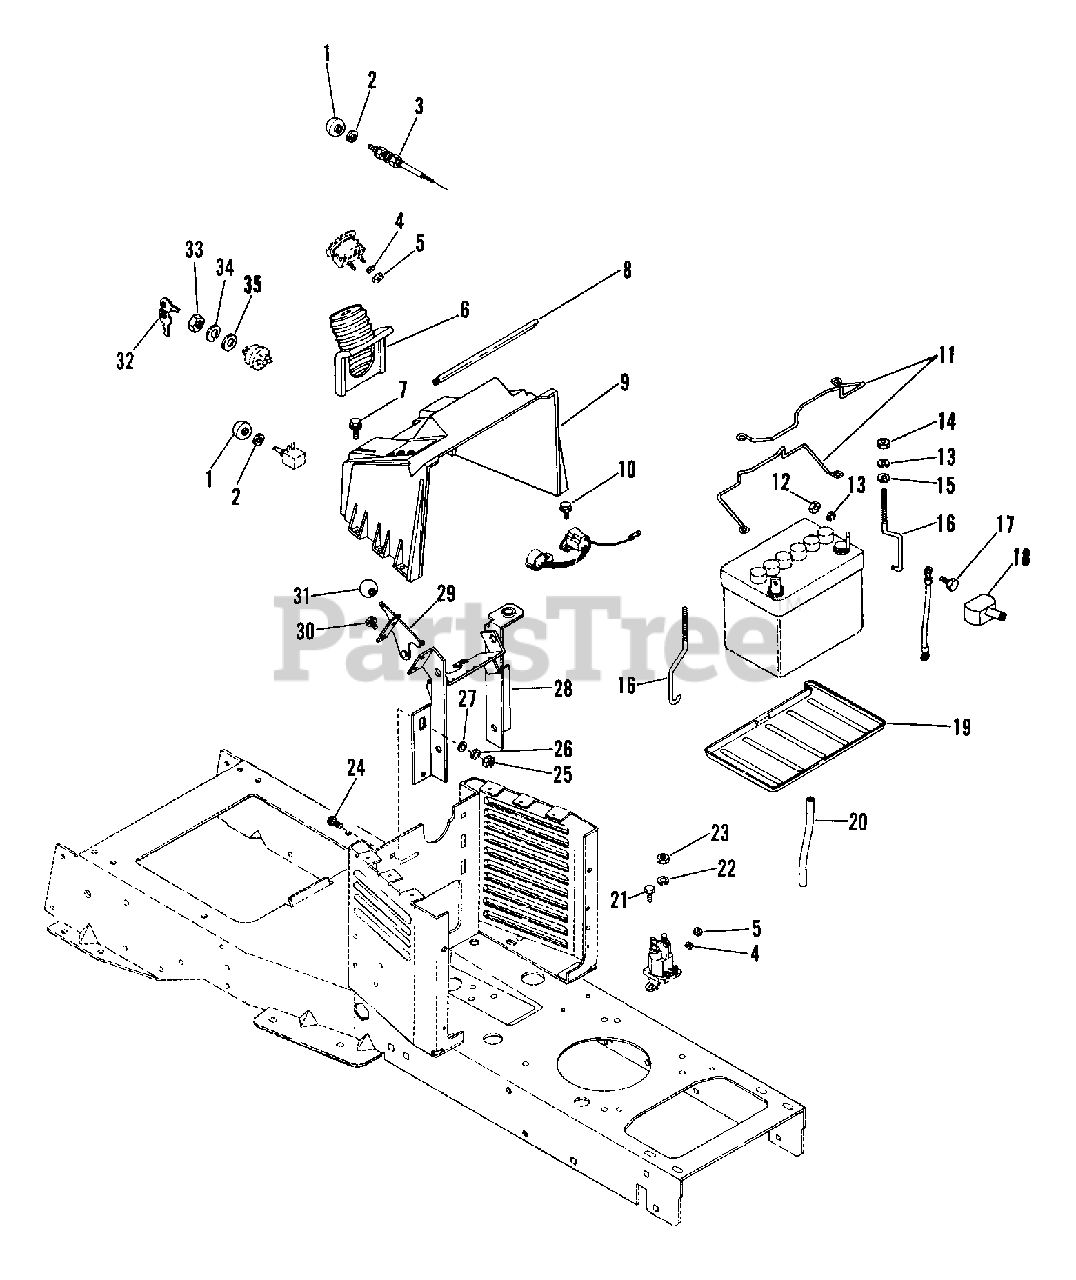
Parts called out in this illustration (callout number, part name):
1	PUSH/PULL CONTROL KNOB
2	WSHR-FL-STL .382X.812X.023 PL
3	CHOKE CONTROL
4	WSHR-LK-EXT #10 ID X .022
5	NUT 10-32 PL
6	STEERING COLUMN BOOT
7	SCR-TAP 10-16X.50 HWH PL AB
9	DASH ASSEMBLY
10	SCR-TAP 10-24X.375 CRPH 1A
11	HOLD DOWN
12	NUT-HEX .250-20 PL
13	WSHR-LK .250X.077 HVY PL
14	NUT-LK-NYL .250-20 PL
15	WSHR-FL-STL.281X.62X.065 PL
16	TIE DOWN
17	BLT-HEX .25-20X.63 PL GR2
18	INSULATOR
19	BATTERY TRAY
20	DRAIN HOSE
21	SCR-TAP .250-20X.37 HWH PL TR
22	WSHR-LK-INT .313X.030 PL
23	NUT-JAM .312-24 PL
24	BLT-RDHDSQNK .312-18X.62SHTPL
25	NUT-HEX .312-18
26	WSHR-LK .312X.097 PL HVY
27	WSHR-FL-STL.312X.734X.065PL
28	CONTROL SUPPORT
29	THROTTLE CONTROL
30	SCR-TAP 10-24X.375 HWH PL TR
31	THROTTLE CONTROL KNOB
32	KEYS
33	NUT .562-24
34	WSHR-LK-INT .563X.040 PL
35	WSHR-FL-STL .880X1.380X.062
